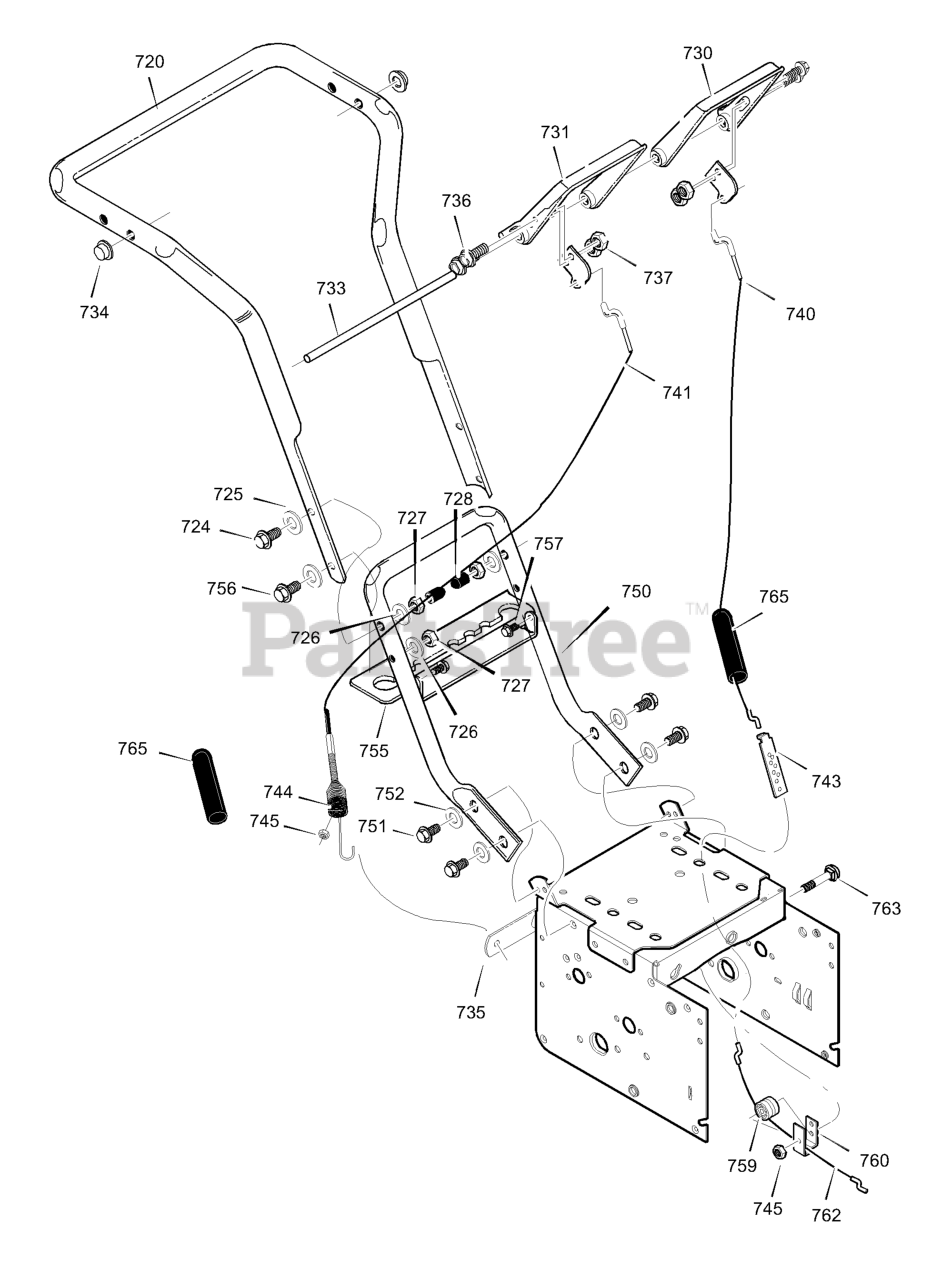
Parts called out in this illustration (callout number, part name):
724	SCREW
725	WASHER, FLAT
726	WASHER
727	NUT
728	PLASTIC-STOP
730	CLUTCH, LEFT HANDLE CONTROL
731	CLUTCH, RIGHT HANDLE CONTROL
733	ROD, PIVOT HANDLE
734	PUSH ON CAP
735	PLATE, CABLE PIVOT
740	CABLE, CLUTCH
741	CABLE, AUGER CLUTCH
743	BRKT, CABLE ADJUST
744	SPRING, AUGER CLUTCH
745	LOCKNUT
750	HANDLE, LOWER
751	SCREW
752	WASHER
755	BRACKET, GEAR SELECTOR
756	SCREW
757	SCREW, 1/4-20 x .63
759	SPOOL-CABLE, AUGRT CLUTCH
760	BRACKET, CABLE SPOOL YZ
762	CABLE, LOWER DRIVE 12"
763	BOLT, HEX 1/4-20 X 1.75 YZ
765	BOOT, CLUTCH SPRING
